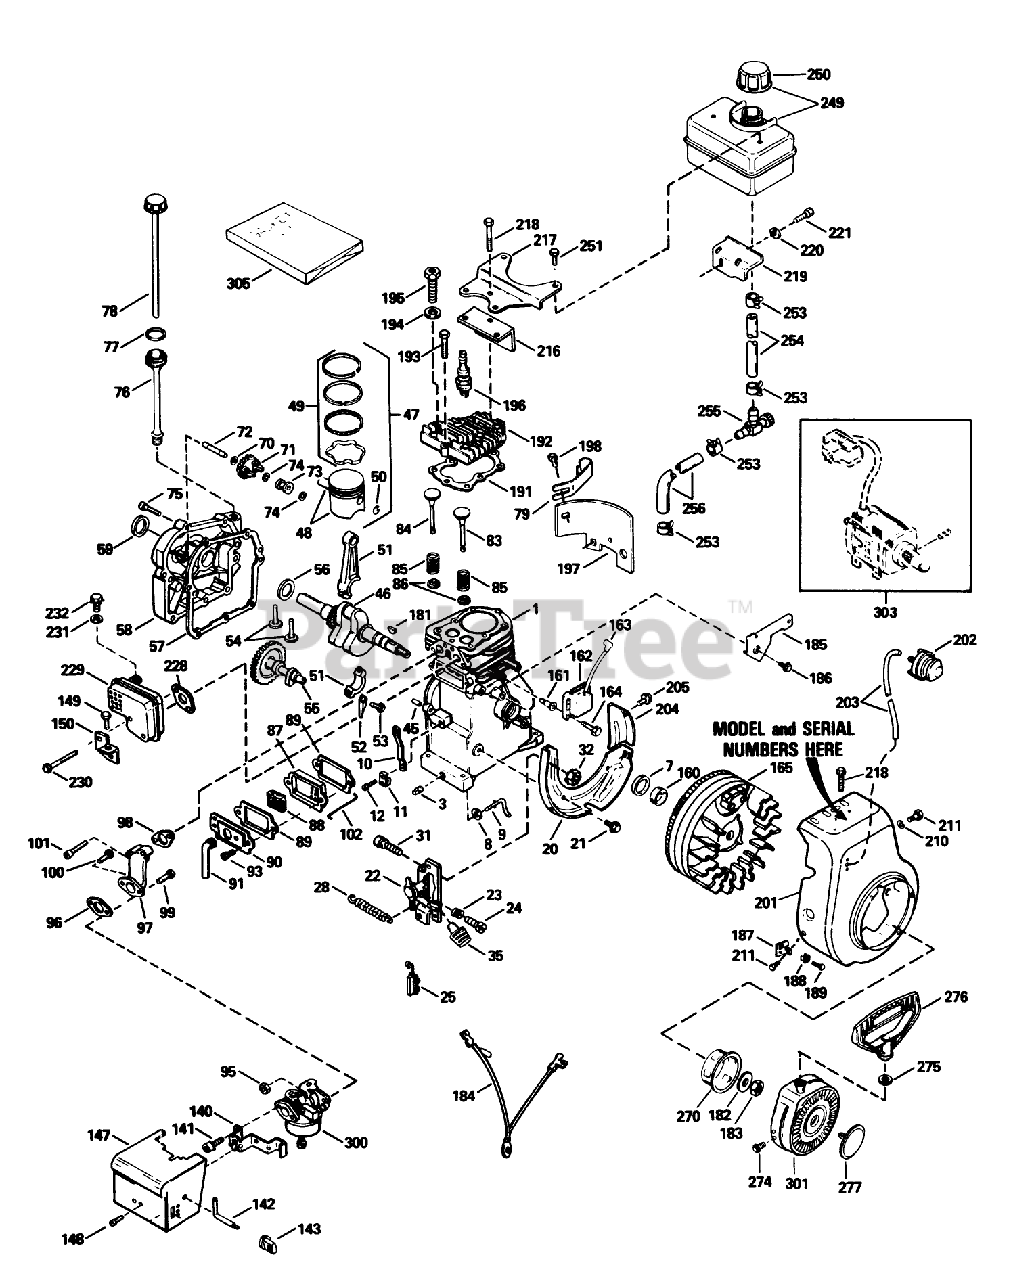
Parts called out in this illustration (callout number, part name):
1	Cylinder Assembly (Incl. Ref. #3, 7 45)
3	Plug-Drain, Oil (SQH 1/4-18)
7	Seal-Oil
8	Washer-Flat
9	Rod-Governor
10	Lever-Governor
11	Clamp-Lever, Governor
12	Screw
20	Baffle-Blower Housing
21	Screw (1/4-20x19/32)
22	Control Assembly, Speed (Incl. Ref. #155 thru 158 160)
23	Spring-Compression
24	Screw
25	Terminal
28	Spring-Extension
31	Screw
32	Nut-Lock
35	Knob-Control
45	Pin-Dowel
46	Crankshaft ASM
47	Piston, Pin Ring Assy., (Incl. Ref. #15 16) (Std.)
47	Piston, Pin Ring Assy., (Incl. Ref. #15 16) (.010 Oversize)
47	Piston, Pin Ring Assy., (Incl. Ref. #15 16) (.020 Oversize)
48	Piston Pin Assy. (Incl. Ref. #16) (Std.)
48	Piston Pin Assy., (Incl. Ref. #16) (.010 Oversize)
48	Piston Pin Assy. (Incl. Ref. #16) (.020 Oversize)
49	Ring Set-Piston Std.
49	Ring Set-Piston .010 oversize
49	Ring Set-Piston .020 oversize
50	Ring-Retaining, Piston Pin
51	Rod Assembly, Connecting (Incl. Nos. 17 18)
52	Dipper-Oil
53	Bolt-Rod, Connecting
54	Lifter-Valve
55	Camshaft
56	Washer-Thrust
57	Gasket-Cover, Cylinder
58	Cover-Cylinder (Incl. Ref. #59 72)
59	Seal-Oil
70	Washer
71	Governor Gear ASM
72	Shaft-Governor
73	Spool-Governor
74	Ring-Retaining
75	Screw (1/4-20 x 1-1/4)
76	Tube-Fill, Oil
77	O-Ring
78	Dipstick
79	Clip-Tube, Fill
83	Valve, Exhaust (Std.)(Incl. No. 40)
83	Valve, Intake (1/32" oversize)(Incl. No. 40)
84	Valve-Intake Standard (Incl. Ref. #151)
84	Valve-Intake 1/32" oversize (Incl. Ref. #151)
85	Spring-Valve
86	Cap-Valve, Spring
87	Body-Breather
88	Element-Breather
89	Gasket-Cover, Valve
90	Cover-Breather
91	Tube-Breather
93	Screw
95	Nut and Lock Washer (1/4-28)
96	Gasket
97	Pipe-Intake
98	Gasket-Intake
100	Screw (1/4-28 x 1-11/16)
101	Screw (1/4-20 x 1-19/32)
102	Link-Governor to Throttle
140	Bracket-Choke
141	Screw (10-32 x 1/2)
142	Rod-Choke
143	Knob-Control
147	Cover-Carburetor
148	Screw (8-32 X 5/16)
149	Screw (10-24 x 3/8)
150	Bracket-Cover, Carburetor
160	Spacer
162	Solid State
163	Cover-Spark Plug
164	Screw
165	CLAMP
181	Key-Flywheel
182	Washer-Belleville
183	Nut-Flywheel
184	Wire-Ground
185	Bracket-Hold Down
186	Screw (10-24 x 9/16)
187	Bracket
188	Grommet
189	Screw (8-32 x 3/8)
191	Gasket-Cylinder Head
192	Head-Cylinder (Incl. Ref. #218)
193	Screw (5/16-18x1-1/2)
194	Washer-Flat
195	Screw ( 5/16-18 x 1-1/2)
196	Spark Plug-Resistor (R J19 L M)
197	Extension-Blower
198	Screw
201	Housing-Blower
202	Primer-Asm
203	Line-Primer
204	Baffle-Extension
205	Screw-Hex Washer Hd.
210	Washer
211	Screw
216	Baffle-Heat
217	Plate-Fuel Tank
218	Screw (5/16-18 X 2)
219	Bracket-Fuel Tank
220	Washer-Flat
221	Screw Assembly
228	Gasket-Exhaust
229	Muffler
230	Screw-Fil. Hd.
231	Washer
232	Screw
249	Tank Assembly-Fuel (Incl. Ref. #250 253)
250	Cap-Fuel
251	Screw (1/4-15x7/8)
253	Clamp-Line, Fuel
254	Line-Fuel (8.62)
255	Valve-Shut Off
256	Line-Fuel
270	Cup-Starter
274	Screw, Hex Hd.
275	Washer
276	Handle-Starter, Mitten Grip
277	Plug Starter
300	Carburetor (Incl. Ref. #96)
301	Rewind Starter
303	Motor-Electric Starter
305	Gasket Set (Incl.Items Marked *)
